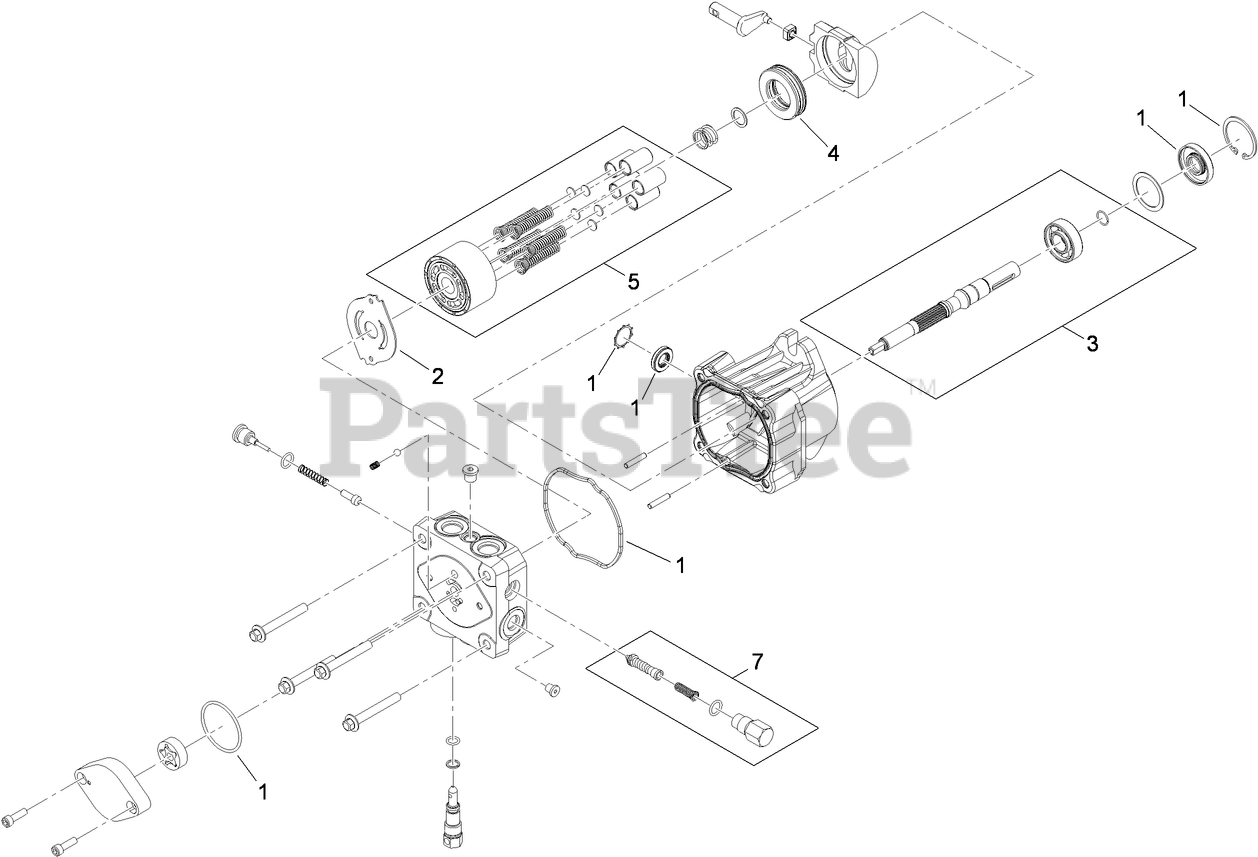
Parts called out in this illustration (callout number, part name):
1	SEAL OVERHAUL KIT
2	Plate-Valve
3	INPUT SHAFT KIT
4	BEARING-THRUST
5	CYLINDER BLOCK KIT
7	SHOCK VALVE KIT
